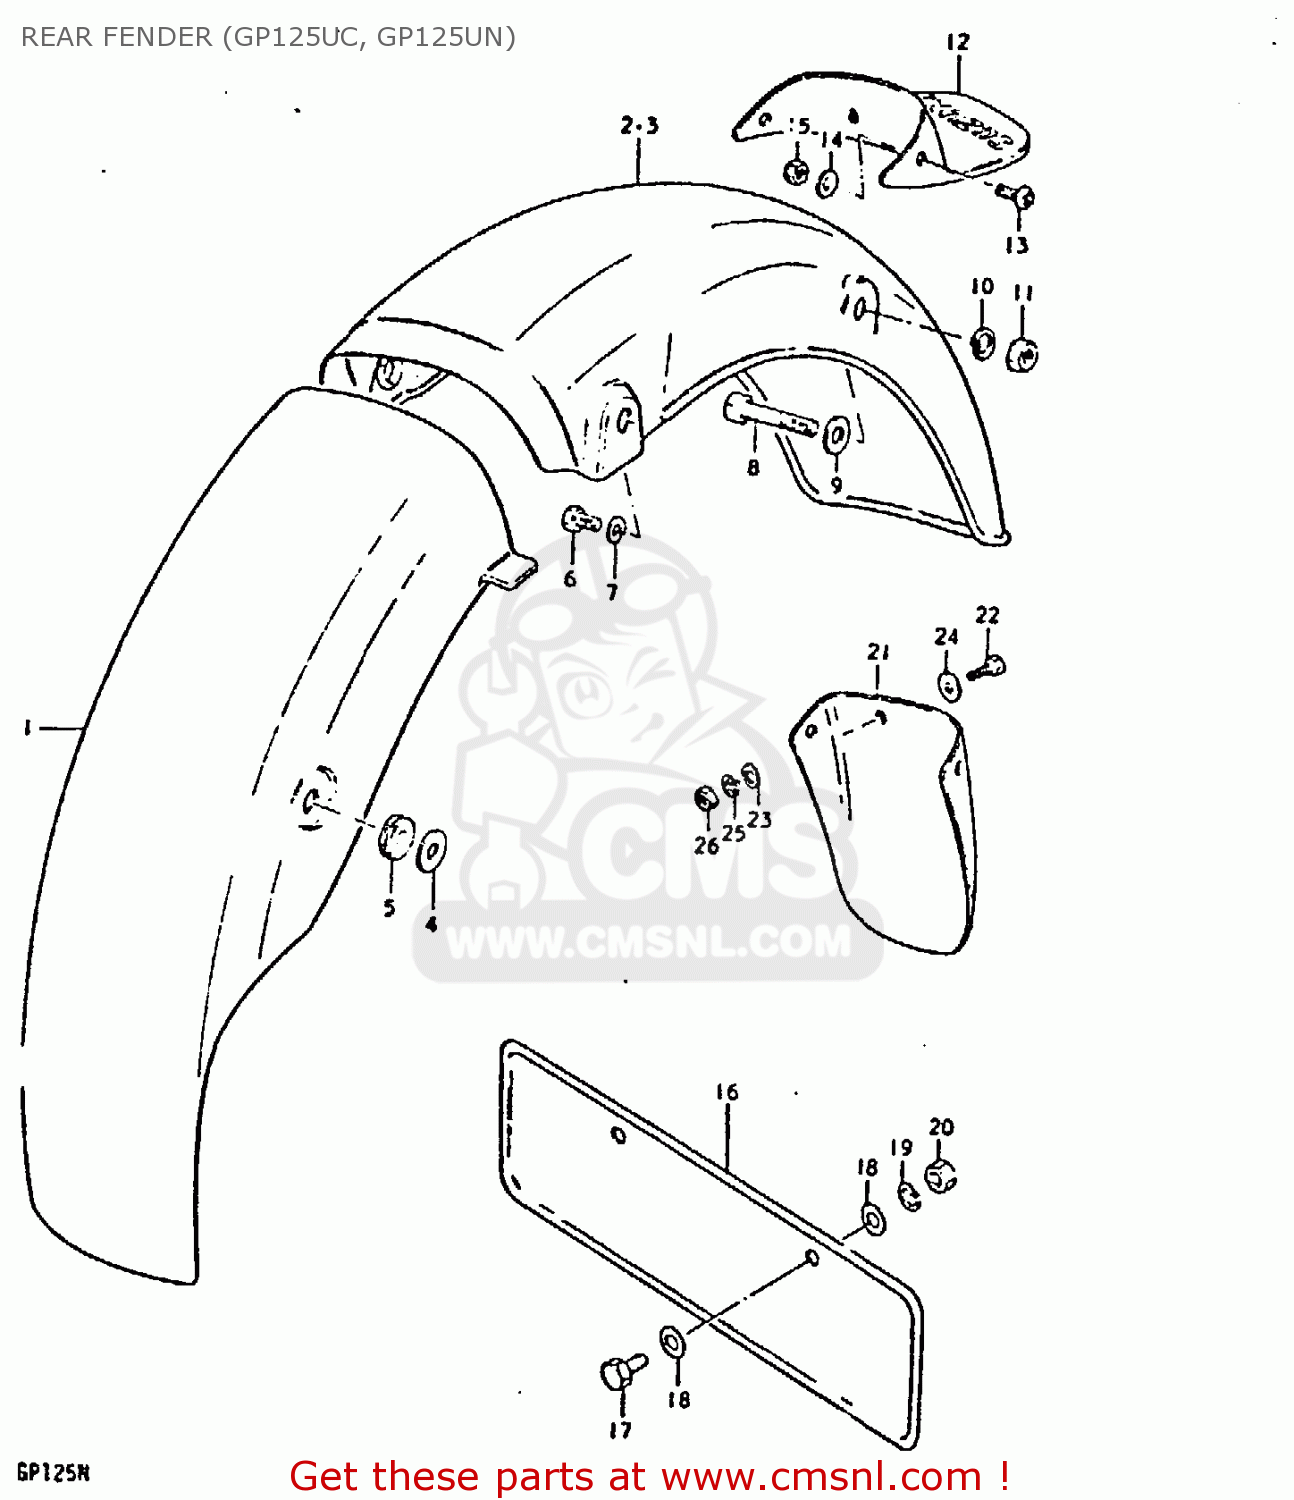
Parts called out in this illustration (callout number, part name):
1	BODY, REAR FENDER FRONT
3	BODY, REAR FENDER REAR (SILVER)
4	WASHER
5	CUSHION
6	BOLT
7	LOCK WASHER
8	BOLT 8X45
9	WASHER
10	LOCK WASHER
11	NUT
21	MUD FLAP
22	BOLT, UPPER
23	WASHER
24	WASHER
25	LOCK WASHER
26	NUT
